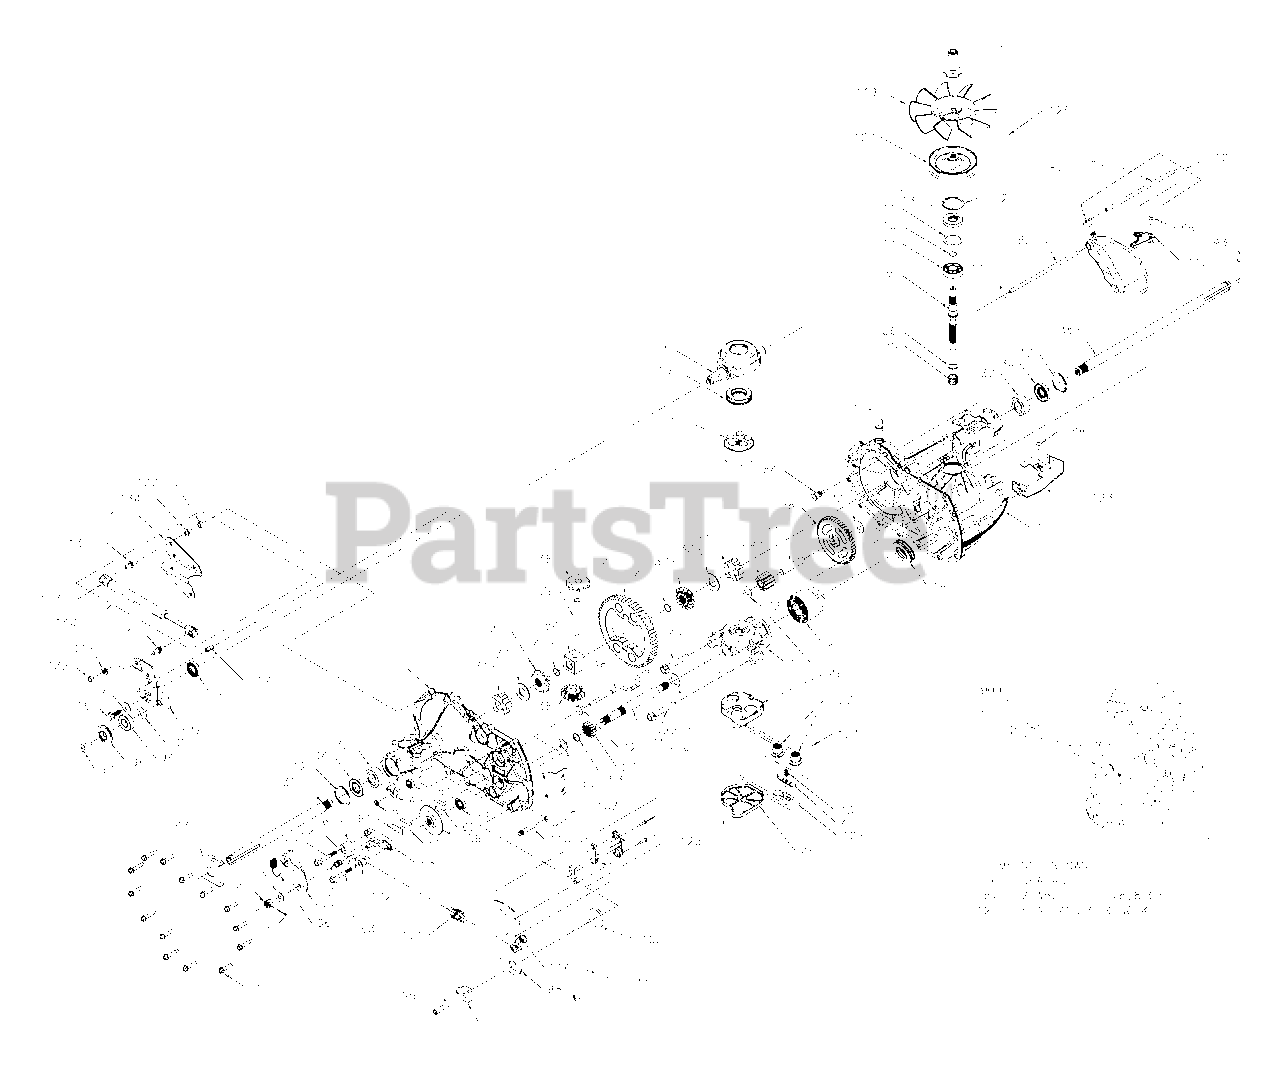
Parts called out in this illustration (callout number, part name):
1	Kit, main housing Main housing, machined
2	Kit, side housing
2	Side housing, machined
3	Kit, center section Center section, machined
4	Swashplate, trunnion machined
5	Kit, cylinder block (1000)
5	Block - cylinder
5	Piston,
5	Spring, compression
5	Washer thrust
6	Sealant tube
7	Hex flange screw 1/4-20 x 1.25
9	Shaft, input
10	Retaining ring
11	Spacer
12	Retaining ring
13	Seal, lip .67 X 1.58 X .276
14	Bearing, ball 6203 (BDR)
16	Hex flange head screw 1/4-20 x 1.25
17	Seal, lip 18 x 32 x 7
18	Arm, control
19	Bearing, thrust (10cc)
23	Check plug assembly, .027 Washer
24	Shaft motor
27	Gear, pinion, 13T
28	Gear 1 OT / 48T
29	Gear, 1 OT jackshaft
30	60T bullgear
31	Sleeve bearing .75 X 1.75 X.625
32	Sleeve bearing (outboard) .75 X 1.575 X.625
33	Washer
34	Lip seal, axle shaft
35	Shaft, axle (keyed, R.H.)
36	Shaft, axle (keyed, L.H.)
37	Miter gear (splined)
38	Miter gear
39	Differential shaft (310-0750)
40	Retaining ring
41	Pin, jackshaft
42	Magnet, ring
43	Spring, bypass
44	Bolt 3/8-24 x 2-1/2
46	Base, filter
47	Actuator, bypass
48	Rod, bypass actuator
49	Arm, bypass
50	Retaining ring.25 External
51	Seal, lip .741 X .25 X .25
52	Washer, fl at 0.050"
53	Retaining ring
54	Bearing, center block
55	Spring, helical compression
56	Washer, block thrust
57	Oil
58	Kit, brake yoke
59	Rotor, brake
60	Brake puck
61	Brake puck plate
62	Pin, brake actuating
63	Hfhcs 1/4-20 x 2 w/patch, special flange
65	Spacer, brake torsion spring
66	Spring, brake arm bias
68	Arm-brake, RH
69	Nut, castle 5/16-24
70	Pin, cotter 3/32x3/4
71	Brake spring
72	Washer (310-0750)
73	Washer, flat
74	Seal, oil
84	Fitting, 5/16 x sae 5/32 tube
85	Hose, expansion tank
87	Cap, barbed vent
88	Bolt, self tapping (BDR)
93	Spring clip, housing
94	Bearing, ball
95	Screw, 5/16-24x 1 1/2 socket head cap
96	Spacer, locating
97	Screw (310-3000)
98	Arm, return
99	Puck, adjusting
100	Washer,.325 Odxl.6 Idx.15 TK
101	Spring, extension
102	Spacer, .56 Odx.26 ID x.87
103	Bracket, torque
107	Deflector
108	Washer, motor shaft.71 ID x 1.150D x.03 Thick
109	Plug, straight thread 9/16-18
110	Screw, torx head 5/16-18
111	O-ring .7 X .301 ID
113	Bracket, support expansion tank
114	Spring guide
117	Pin, spring 5/16 x.75
119	Kit, fan - washer - nut, Fan, 7 in
119	Hex lock nut 1/2-20 (nylon insert)
120	Pulley
123	Belt keeper
124	Center section filter bypass assembly
124	Center section Base filter w/ poppet check plug assembly
124	.027 Washer Spring,
124	bypass actuator,
124	bypass deflector bottom, filter
125	Kit, filter Bottom, filter spring,
125	bypass actuator,
125	bypass deflector
125	Base, filter w/ poppet
126	Kit, fan/pulley, Hex jam 1/20-20 (nylon insert) washer
126	Fan, 7 in,
126	Pulley
127	Kit, seal
127	O-ring .07 X .301 ID
128	Kit, expansion tank, Tank, expansion assembly
128	cap, barbed vent., Bolt,
128	bracket, support expansion tank hose,
128	expansion tank
130	Stud, threaded ball
131	Bracket, cruise/damper
132	Nut 5/16-18
133	Damper
134	Washer, 5/16 lock
140	Kit, damper, Stud, threaded ball bracket,
140	cruise/damper hex nut 5/16-18 NC damper,
140	Washer, helical spring lock 5/16, regular
141	Kit, RCS, Arm, return spring guide switch,
141	RCS activator,
141	RCS switch spring,
141	RCS switch retainer,
900	Transaxle
